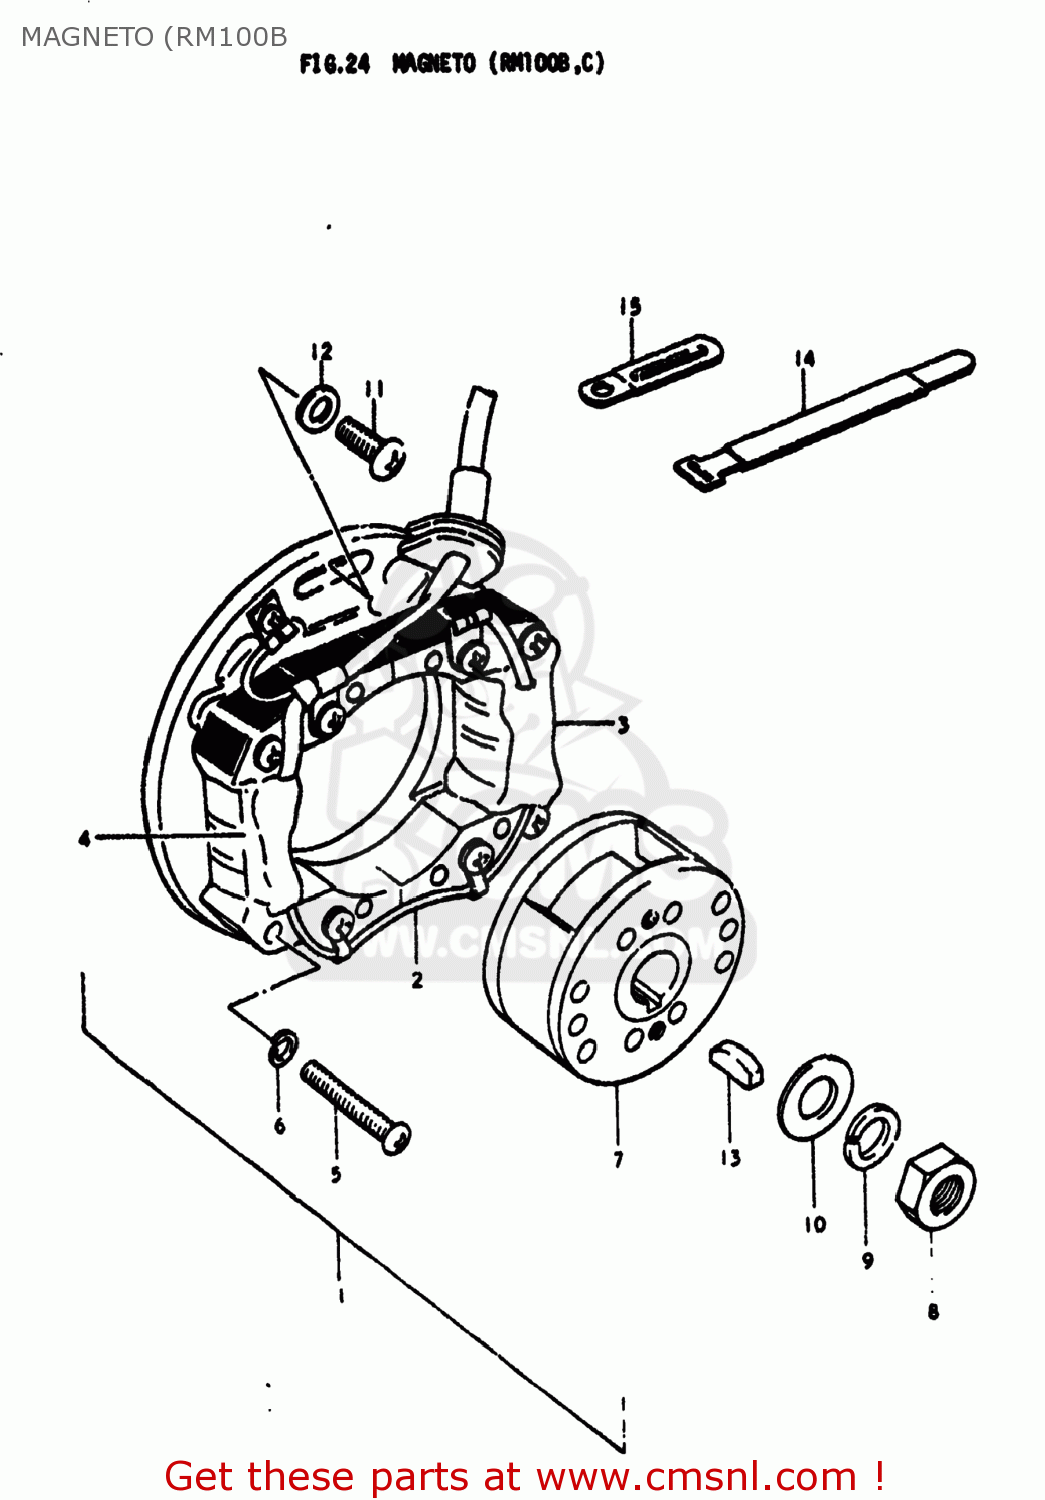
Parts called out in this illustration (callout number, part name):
1	MAGNETO ASSEMBLY
2	STATOR ASSEMBLY
3	COIL,PRIMARY
4	COIL,PULSER
5	SCREW
6	LOCK WASHER
7	ROTOR ASSEMBLY
8	NUT (10MM)
9	LOCK WASHER
10	WASHER
11	SCREW
12	WASHER
13	KEY 4MM
14	CLAMP
15	CLAMP
